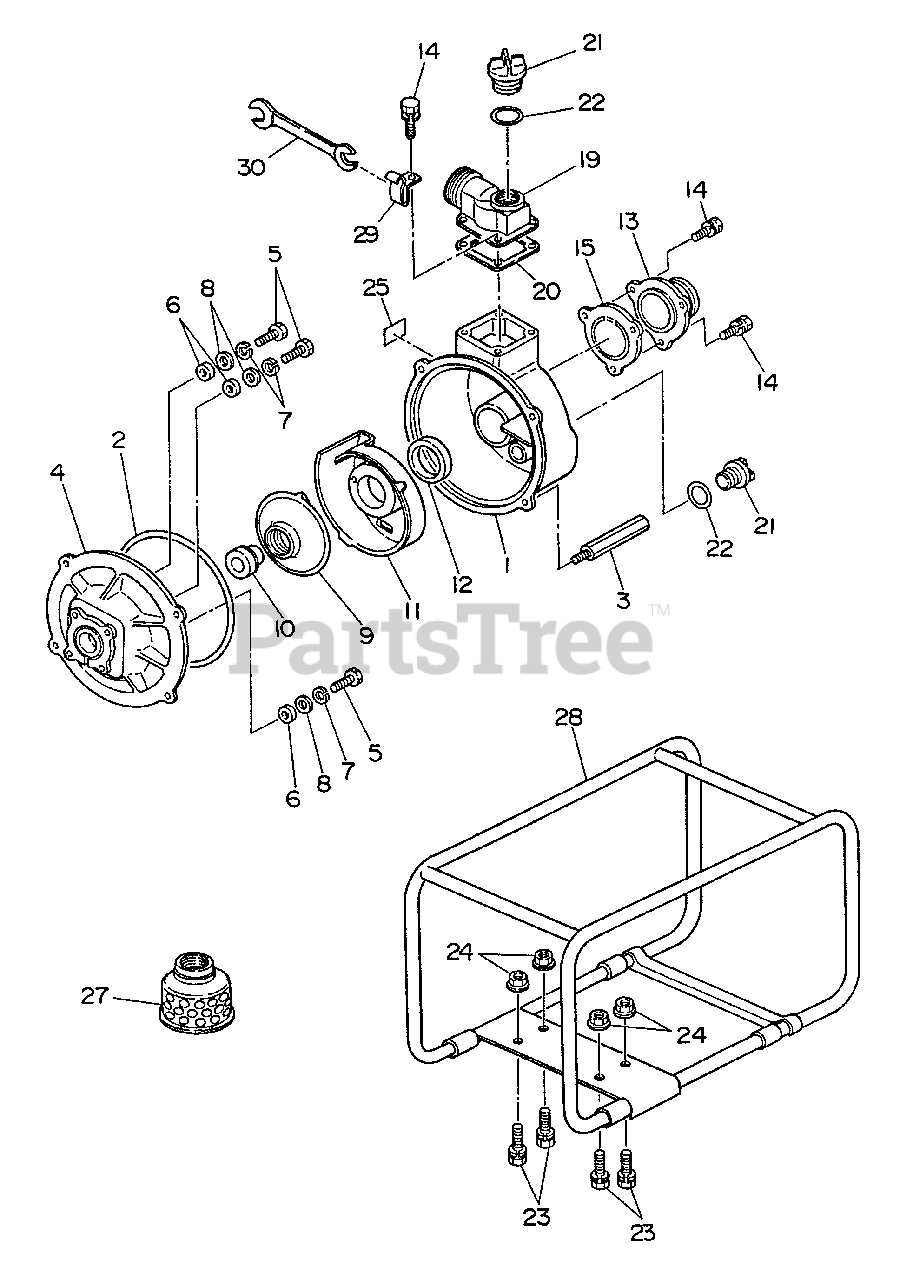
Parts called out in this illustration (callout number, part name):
2	GASKET
3	BOLT
4	COVER, PUMP CASE
6	SEAL PACKING
7	LOCKWASHER
10	SEAL, MECHANICAL
11	INNER CASING
13	SUCTION FLANGE (NPT)
14	BOLT
15	VALVE, CHECK
19	DELIVERY FLANGE (NPT)
20	PACKING, DELIVERY FLANGE
21	PLUG
23	BOLT
24	NUT, FLANGE
25	LABEL, PUMP NAME
27	STRAINER, DEBRIS
28	FRAME
29	HOOK
